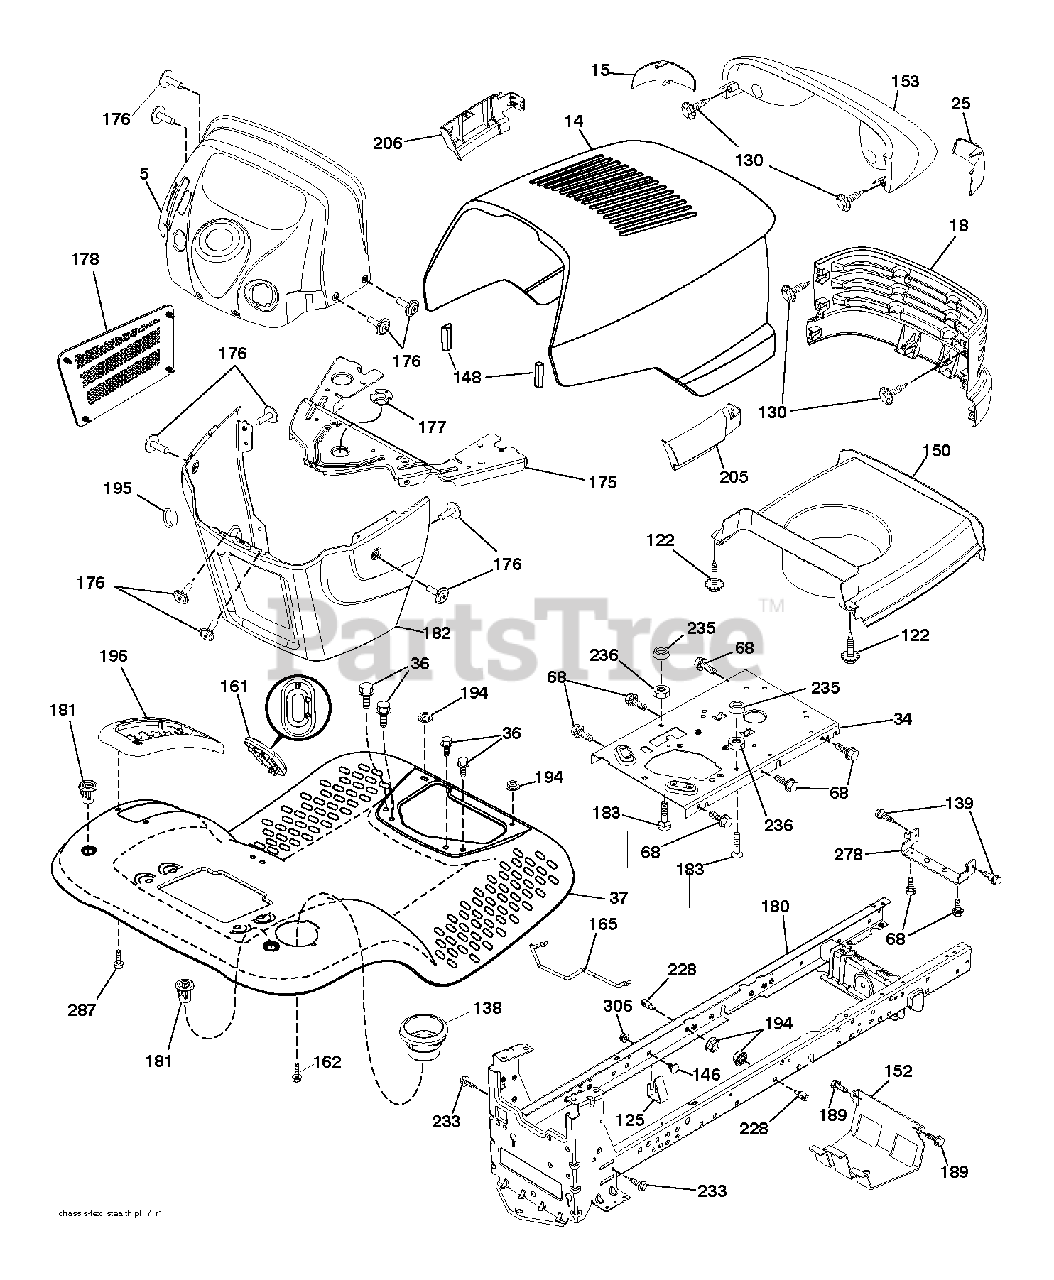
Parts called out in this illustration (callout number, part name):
5	DASH.UPR.STEALTH.BLACK
14	HOOD.ASM.DIXON.STEATH.SRS.BLUE
15	LENS LH
18	GRILLE.STEALTH.GT.BLACK
25	LENS RH
34	PLATE.ENGINE.WELDED.CHASSIS
36	SCREW 5/16"
37	FENDER.TLT.W/CPH.W/FW.666
68	SCREW LT
122	SCREW.WSHD.HEX10-32X5/8
125	CLIP.FUEL.LINE
130	SCREW.#10 X 0.750.BOS (2 2)
138	CUPHOLDER.TL.TEX.BLACK
139	BOLT, SHOULDER 5/16-18
146	BOLT.RDHD.SHT.SQNK.3/8-16X5/8
148	EXTRUSION BUMPER
150	DUCT.HEAT.HOOD.STEALTH.GT
152	SHIELD.BROWNING.W/TEX
153	LIGHTBOX.ASM.STEALTH.DL.DIXON
161	WINDOW.FUEL.LT.TEX.BLACK
162	SCREW.HI-LO.CONSOLE
165	SUPPORT.TANK.REAR.W/TEX
175	CROSSMEMBER.
176	SCREW.#10-24X5/8.RN.QU
177	BUSHING,STEERING
178	CARGO.ASM.NET.DASH.LOWER
180	CHASSIS
181	FEND/FTRST.PCH.CPH.NFW
182	DASH.LOWER.
183	BOLT.5/16-18X1-1/4 FULL THD
189	SCREW
194	NUT LOCK HEX FLANGE 5/16-18
196	CONSOLE.ASM.DECKLFT.BL/RBT.TLT
205	SKIRT.GRILLE.STEALTH.RH
206	SKIRT.GRILLE.STEALTH.LH
228	STUD.FASTNER.W/ANTI-ROTATE
233	BOLT.SHOULDER
235	SPACER FENDER
236	NUT.CENTERLOCK.5/16-
278	BRKT.HOOD/MUFF.STEALTH
287	SCREW 1/4X20
306	NUT LOCK FLG 3/8-16 UNC
